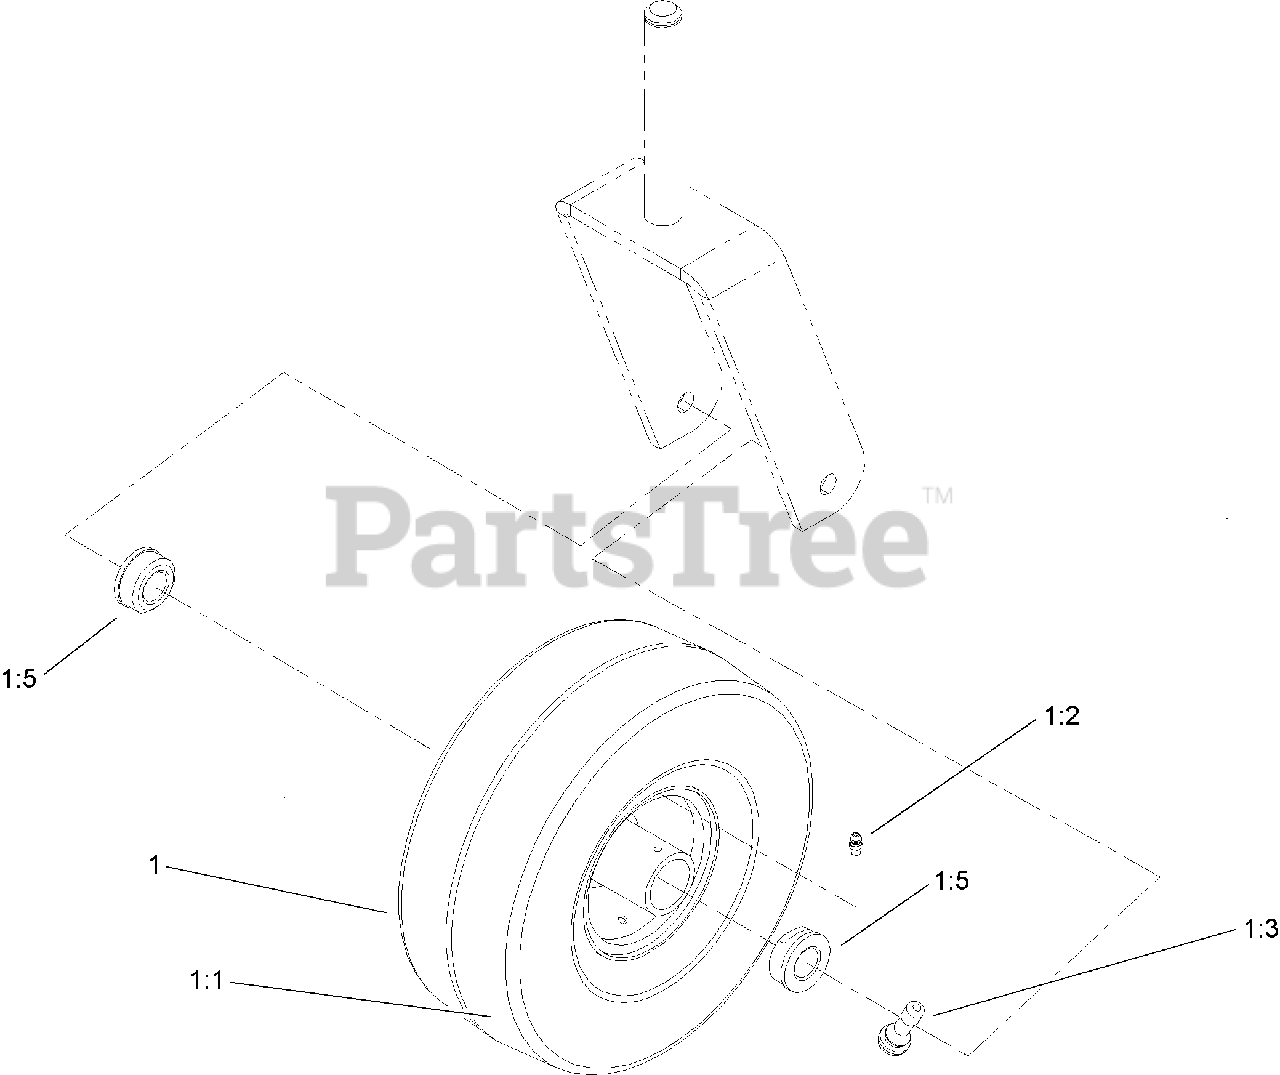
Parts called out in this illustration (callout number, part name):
1	CASTER WHEEL ASM
1:1	TIRE-SMOOTH
1:2	FITTING-GREASE
1:3	STEM-VALVE
1:5	BEARING-OUTSIDE
